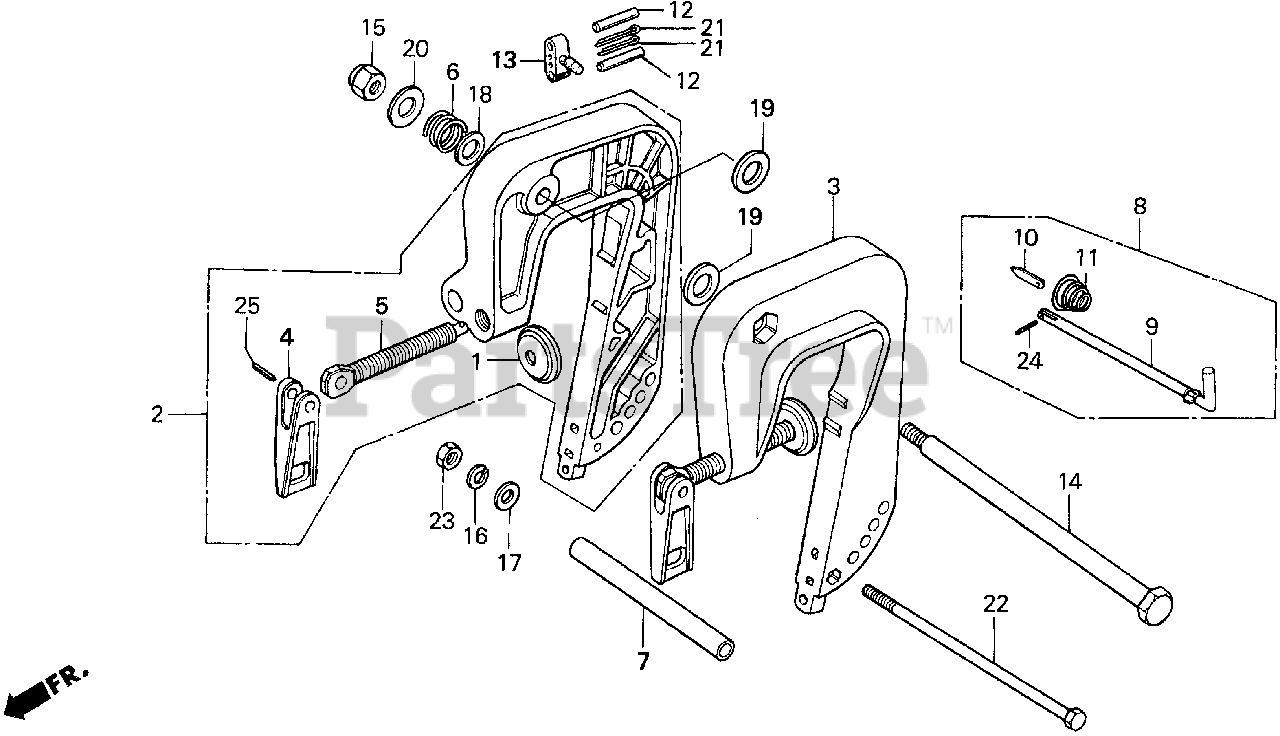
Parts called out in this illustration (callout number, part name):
1	PLATE, PUSH
2	BRACKET, R. STERN *NH282MU* (OYSTER SILVER METALLIC-U)
3	BRACKET, L. STERN *NH282MU* (OYSTER SILVER METALLIC-U)
4	GRIP, CLAMP *NH282MU* (OYSTER SILVER METALLIC-U)
5	SCREW, CLAMP
6	SPRING, TILT
7	COLLAR, DISTANCE (6MM)
8	ROD, ADJUSTING
9	ROD, ADJUSTING
10	STOPPER, ROD
11	SPRING, ADJUSTING ROD
12	PIN, SHEAR
13	HOLDER, PARTS
14	BOLT, TILTING
15	NUT, SELF-LOCK (8MM)
16	WASHER, SPRING (6MM)
17	WASHER, PLAIN (6MM)
18	WASHER, PLAIN (10MM)
19	WASHER (10MM)
20	WASHER (8MM)
21	PIN, COTTER (3MM)
22	BOLT, HEX. (6X160)
23	NUT, HEX. (6MM)
24	PIN, SPRING (2X8)
25	PIN, SPRING (4X14)
